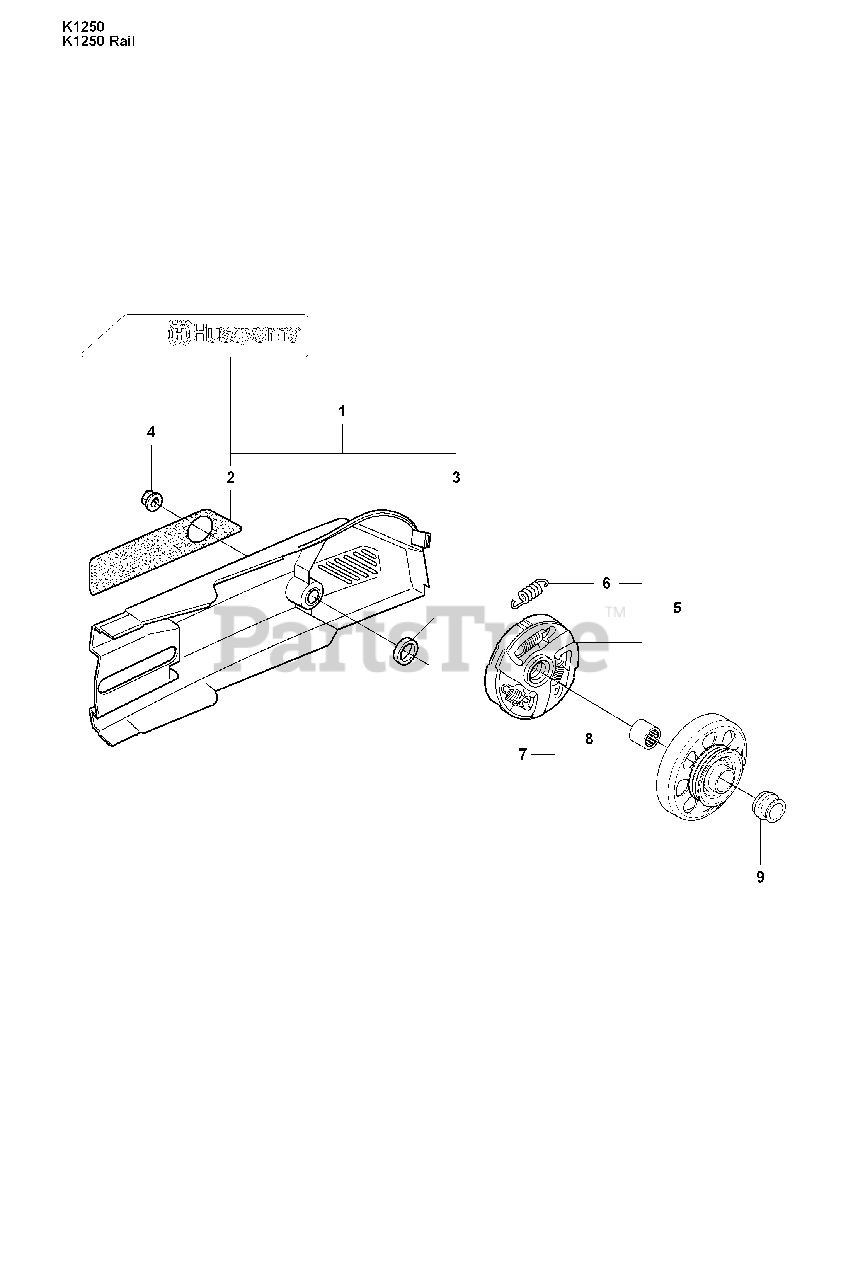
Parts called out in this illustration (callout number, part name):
1	BELT GUARD
3	SPACING SLEEVE
4	NUT FLANGE
5	CLUTCH ASSY
6	CLUTCH SPRING
7	GEAR WHEEL ASSY
8	NEEDLE BEARING
9	SPACING SLEEVE
